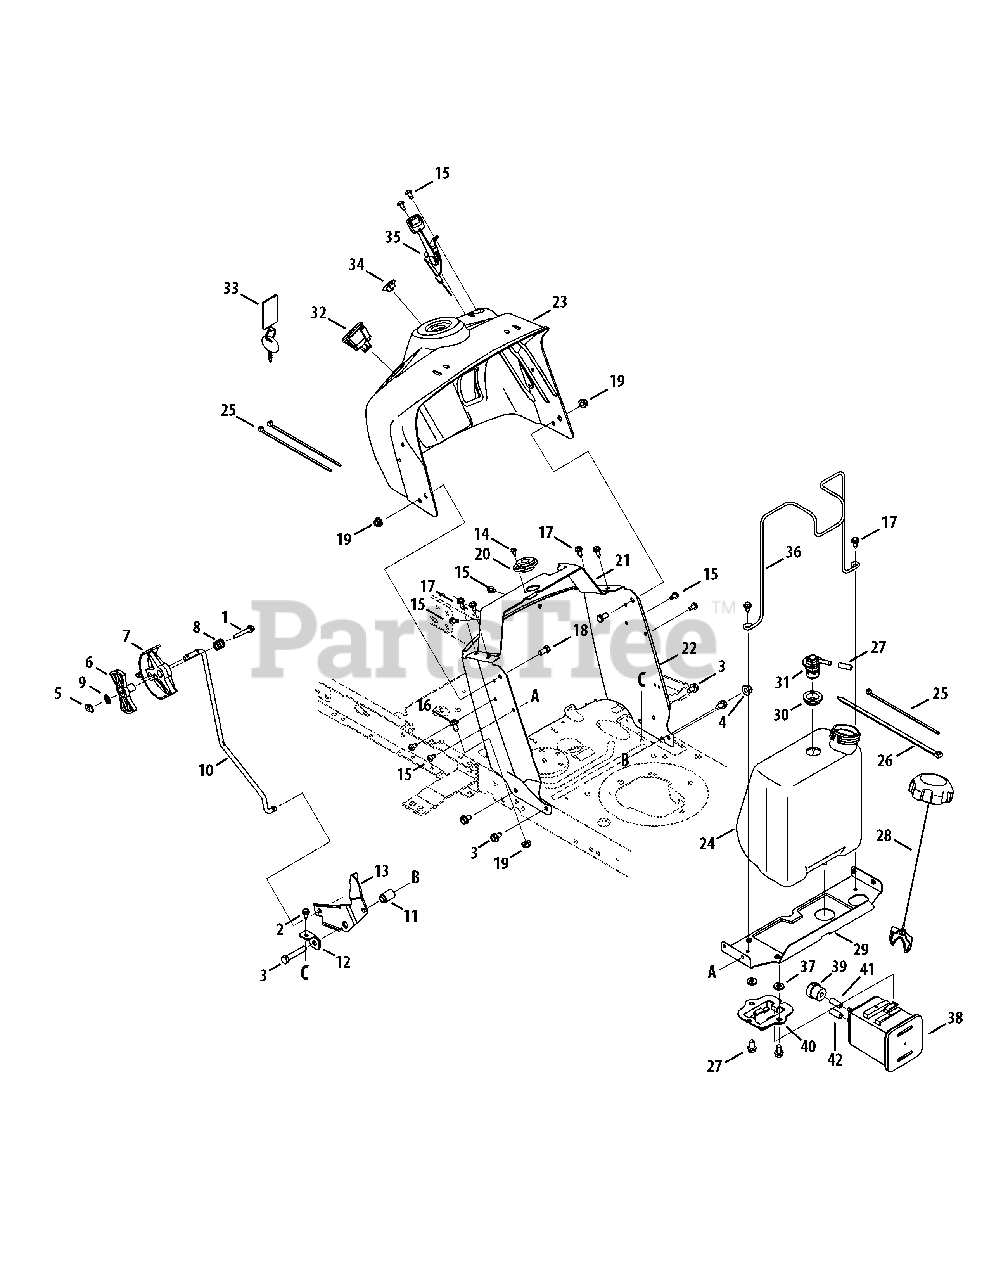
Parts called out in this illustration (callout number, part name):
1	Hex Head Screw, 1/4-20 x 1.50
2	Self-Tap Screw, 1/4-20 x .625
3	Hex Head Screw, 3/8-16 x 2.00
4	Flange Lock Nut, 3/8-16
5	Top Lock Weld Nut, 1/4-20
6	Index Control
7	Shift Lever
8	Compression Spring, .685 x .63
9	Internal Lock Washer, 1/4
10	Speed Control Rod
11	Flange Spacer, .390 x .671 x 1.095
12	Speed Latch Tab
13	Transmission Speed Latch, RMC
14	Screw, #10
15	Self-Tap Screw, 1/4-20
16	Self-Tap Screw, 5/16-18
17	Hex Washer Screw, 1/4-20 x .625
18	Hex Head Screw, 5/16-18
19	Flange Lock Nut, 5/16-18
20	Steering Column Bearing
21	Steering Support Bracket
22	Lower Dash
23	Upper Dash Panel
24	Fuel Tank
25	Cable Tie, 3/16 x 7.4"
26	Cable Tie, 36" Lg.
27	Screw, 5/16-18 x .750
28	Fuel Cap, 2.25", Carb
29	Gas Tank Support Bracket
30	Rubber Grommet
31	Fuel Rollover Valve
32	Key Switch Module
33	Key Assembly
34	Choke Plug
35	Throttle/Choke Assembly
36	Fuel Tank Support Rod
37	Flat Washer, .344 x .750 x .120
38	5 Gallon Carbon Canister
39	Vent Filter Canister
40	Canister Adaptor Bracket
41	Hose, Fuel, Low Perm., White
42	Hose, Fuel, Low Perm., Yellow
